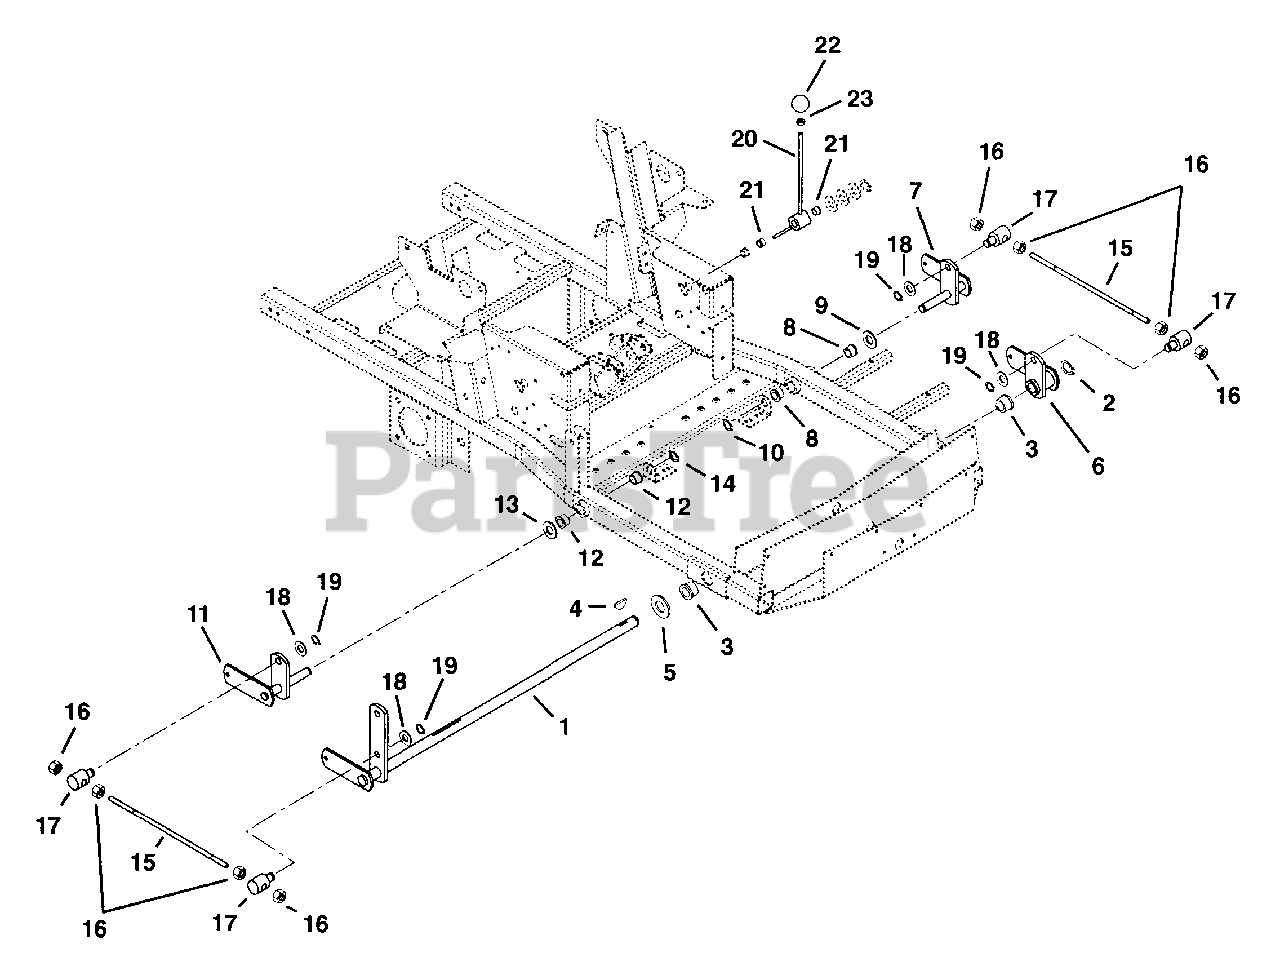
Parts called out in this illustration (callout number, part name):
1	Lift-Mower
2	Ring-Retaining-External 1.00 x .078
3	Bushing-Flange-Nylon 1.020 x 1.385 x .75 x 1.75
4	Key-Woodruff .25 x 1.00
5	Washer-Flat-Steel 1.063 x 2.00 x .134
6	Weldment, Lift Arm-Front
7	Weldment, Lift Arm-Shaft-Left Hand
8	Bushing-Flange-Nylon .762 x 1.0 x .580 x 1.48
9	Washer-Hardened-Steel .758 x 1.23 x .031
10	Ring-Retaining-External .689 x .077
11	Weldment, Lift Arm Shaft-Right Hand
12	Bushing-Flange-Nylon .762 x 1.0 x .580 x 1.48
13	Washer-Hardened-Steel .755 x 1.23 x .031
14	Ring-Retaining-External .689 x .077
15	Rod-Lift Assist
16	Nut-Hex .50-13
17	Pivot-Mower Lift
18	Washer-Flat-Steel .630 x 1.005 x .062
19	Ring-Retaining-External .625 x 050
20	Lever-Deck Lift
21	Bushing-Flange .630 x 1.000 x .625
22	Knob-Steering Lock
23	Nut-Hex-Jam .375-16
